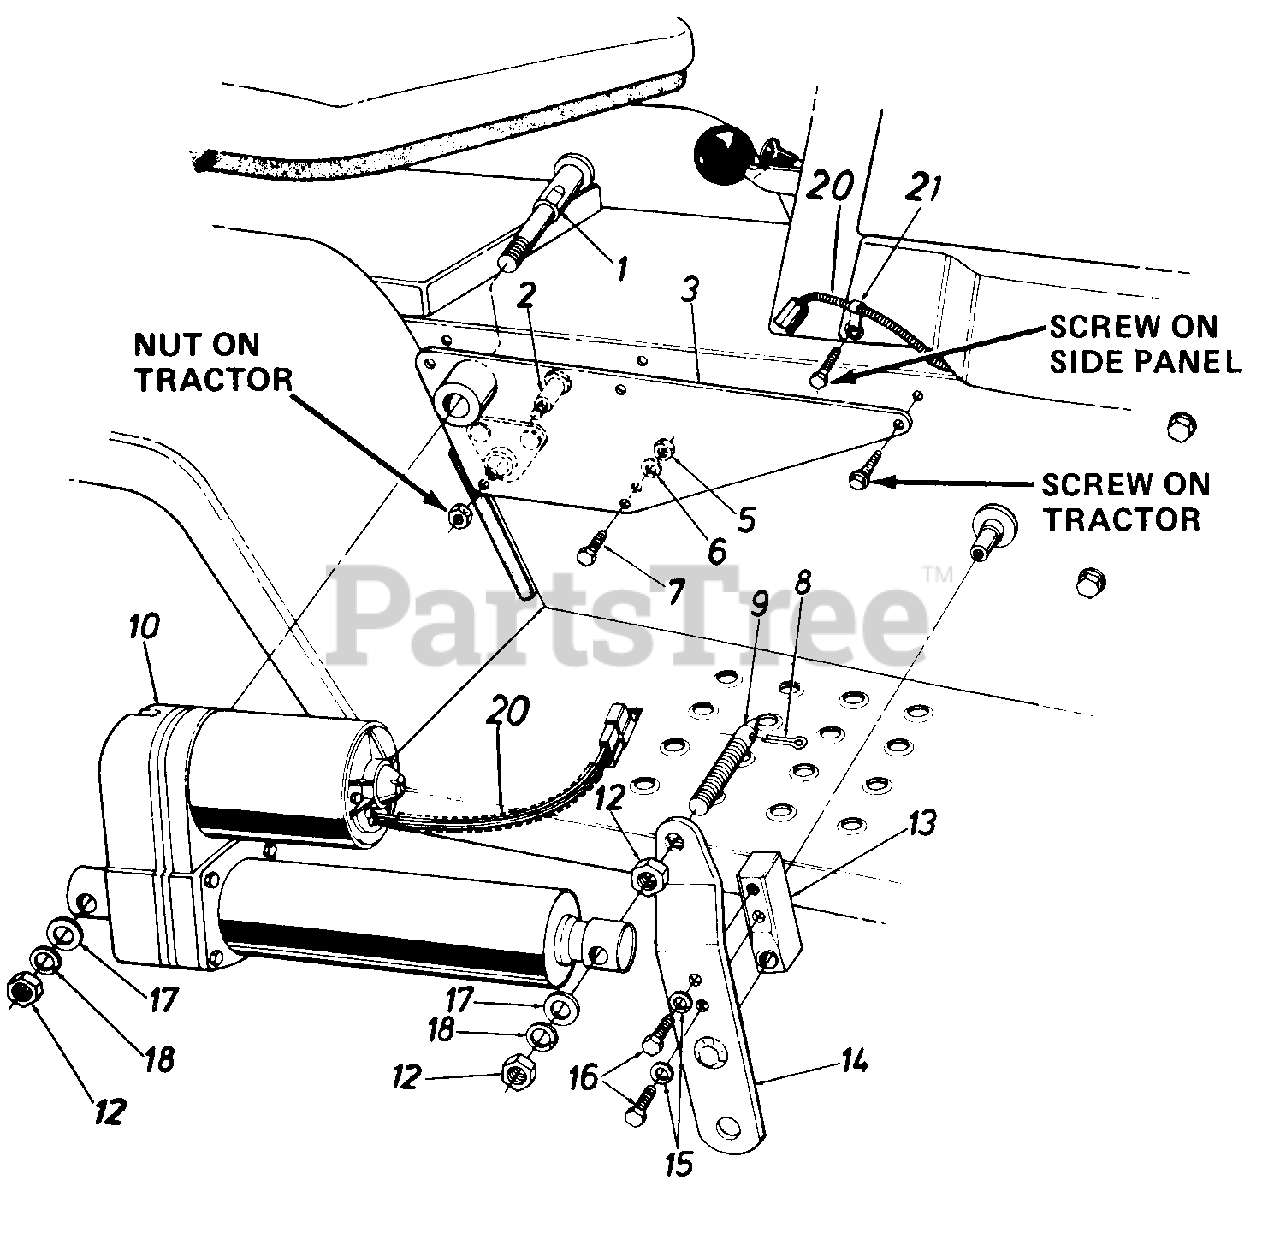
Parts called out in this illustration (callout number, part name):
1	Pivot Pin
2	Shld. Bolt.626 Dia. x.96"
5	Hex Nut 1/4-28 Thd.
6	L-Wash. 1/4" I.D.
7	Hex Bolt 1/4-28 x .75" Lg. (Grade 5)
8	Cotter Pin
9	Indicator & Mtg. Pin
10	Electric Actuator
12	Hex Jam Nut 1/2-13 Thd.
13	Lift Shaft Drive
16	Hex Bolt 5/16-24 x 1 .0" Lg. (Grade 5)
17	Fl-Wash. .53" I.D. x.93" O.D.
18	L-Wash. 1/2" I.D.
20	Plastic Tubing-7"
21	Clamp
